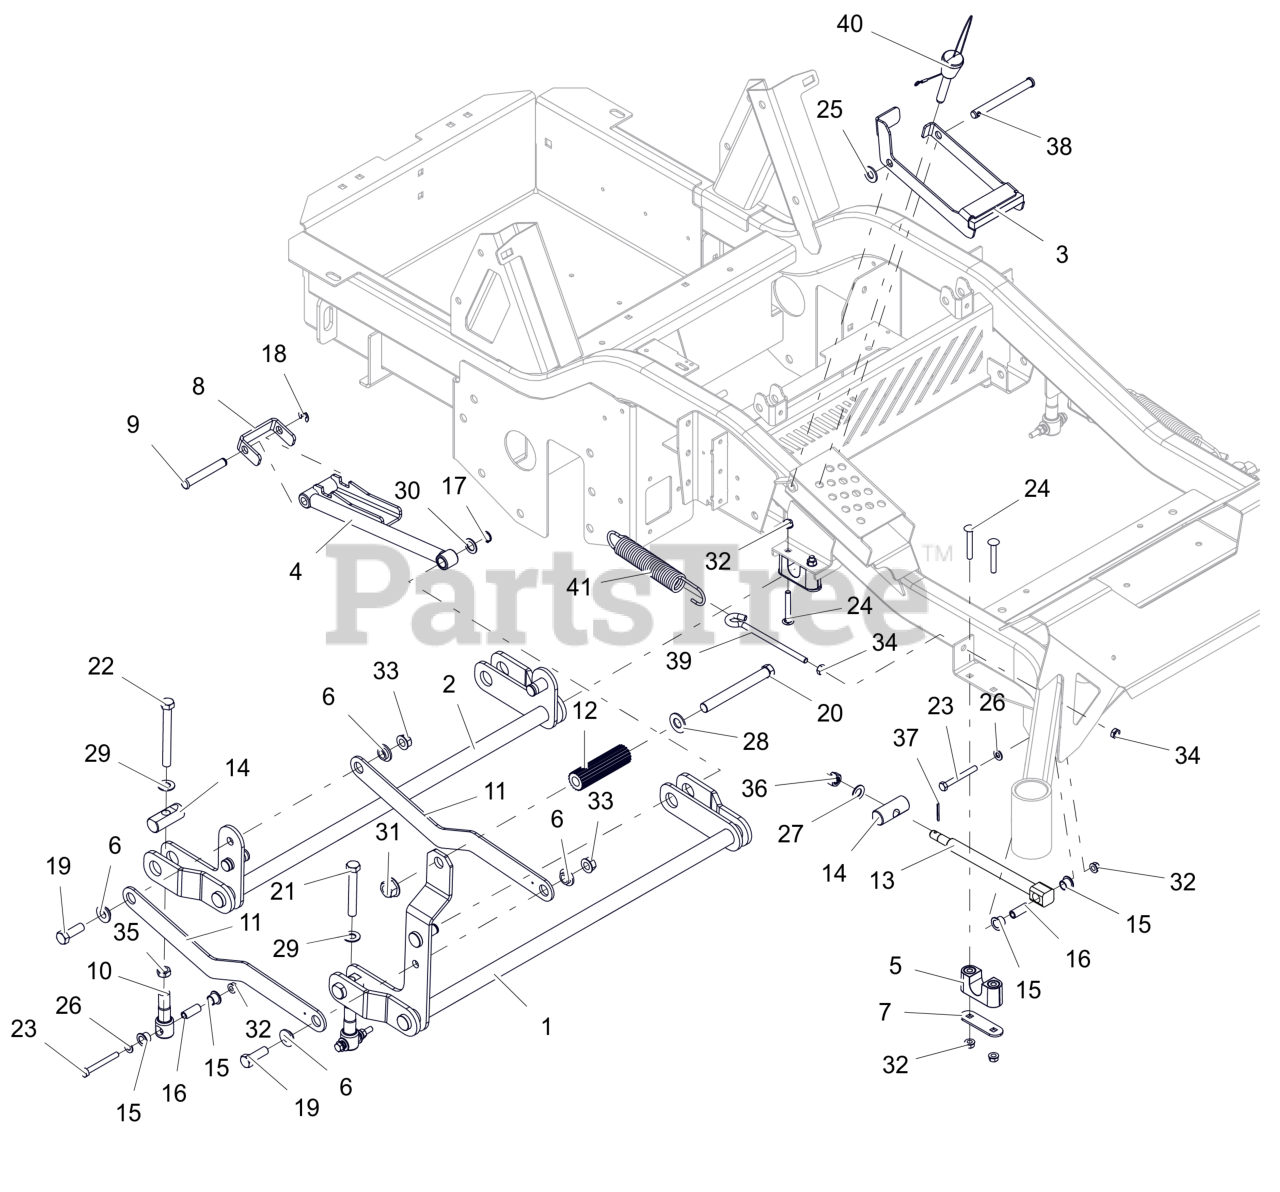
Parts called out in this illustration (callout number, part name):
1	WLDMT, FRONT DECK LIFT PIVOT
2	WLDMT, REAR DECK LIFT PIVOT
3	WLDMT, HOC TRANSFER LOCK (BLACK)
4	WLDMT, HOC LIFT ARM (BLACK)
5	ASM-BUSHING, DECK LIFT
6	BSHG-FLG .515X.750X.310X1.120
7	PLATE, BEARING SUPPORT
8	BRKT, HOC LINE
9	PIN, .499/.494 x 3.385 CLEVIS
10	LINK, DECK LIFT FORMED
11	LINK, DECK
12	ROD, FOOT PEDAL (BLACK)
13	DRAG,LINK-HD
14	PIN, DECK LIFT
15	BSHG, FLANGED .50X.625X.50X.062
16	SPCR, .31X.50X1.265
17	RG-RTNG-EXT .625X.050
18	RG-RTNG-EXT .500X.042 (E)
19	BLT,HEX .50-13X1.50 G5 ZCC
20	BLT, HEX .62-11X5.50 G5 FBP
21	BLT, HEX 0.5-13X3.5F GR5 ZCC
22	BLT, HEX .50-13X4.50F G8 ZCC
23	BLT, HEX .31-18X2.75 G5 ZCC
24	BLT, RHSSN.31-18X2.25 G5 ZCC
25	WSHR,FLT .531X1.062X.095 ZCC
26	WSHR,FLT .344X.688X.065 ZCC
27	WSHR, BLVL .505 X 1.000 X .073 ZCC
28	WSHRFLT 5/8SAE CARBHARD FBP
29	WSHR, FLT .557X1.040X.102 ZCC
30	WSHR, FLT .630X1.005X.062 ZCC
31	NUT,FLG-TOP LK .625-11 FBP
32	NUT,LK-CTR-FLG .31-18 GF ZCC
33	NUT-LK-CTR-FLG .500-13 GG ZCC
34	NUT-JAM .375-16 G2 ZCC
35	NUT-JAM .500-13 G2 ZCC
36	NUT-SL .50-13
37	PIN,CTR.12X1.25EXTPRSQCT ZC120
38	PIN, SLIC-.500X4.97X4.55 -ZC
39	BOLT,.38-16 X 5.25-.62 DIA EYE
40	PIN, MAGNETIC .50X2.50
41	SG-TENS .162X1.25X8.25 WLD 25
